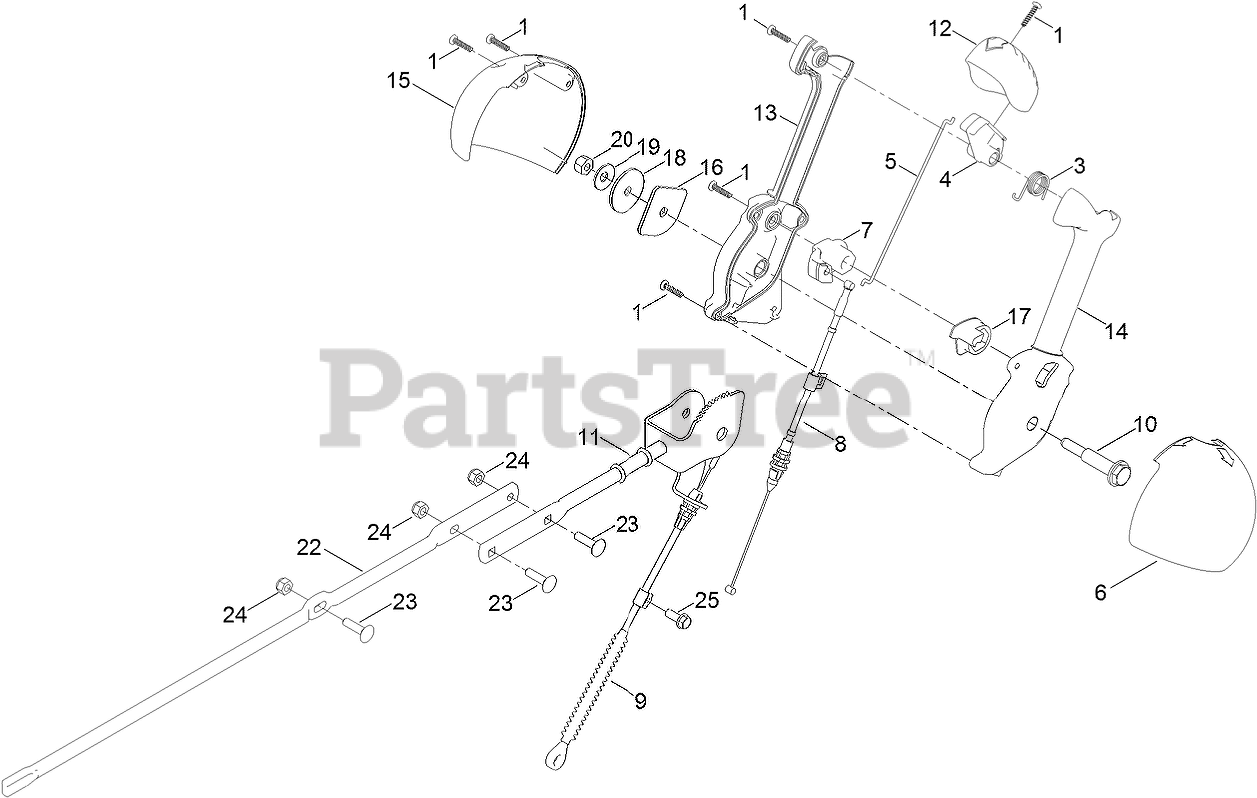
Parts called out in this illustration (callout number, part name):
1	SCREW-PPH
3	SPRING-TORSION
4	TRIGGER-LATCH
5	LINK-LATCH
6	COVER-LEVER, CHUTE (LH)
7	LEVER-CABLE, DEFLECTOR
8	CABLE-RELEASE, CHUTE
9	CABLE-CONTROL, DEFLECTOR
10	SCREW-SHOULDER
11	CHUTE CONTROL ROD
12	CAP-LEVER
13	LEVER-CONTROL, CHUTE (RH)
14	LEVER-CONTROL, CHUTE (LH)
15	COVER-LEVER, CHUTE (RH)
16	PLATE-FRICTION
17	PAWL-LATCH
18	WASHER-NYLON
19	WASHER-BELLEVILLE
20	NUT-LOCK, NI
22	ROD-CHUTE
23	SCREW-CARR
24	NUT-LOCK, NI
25	SCREW-HWH
